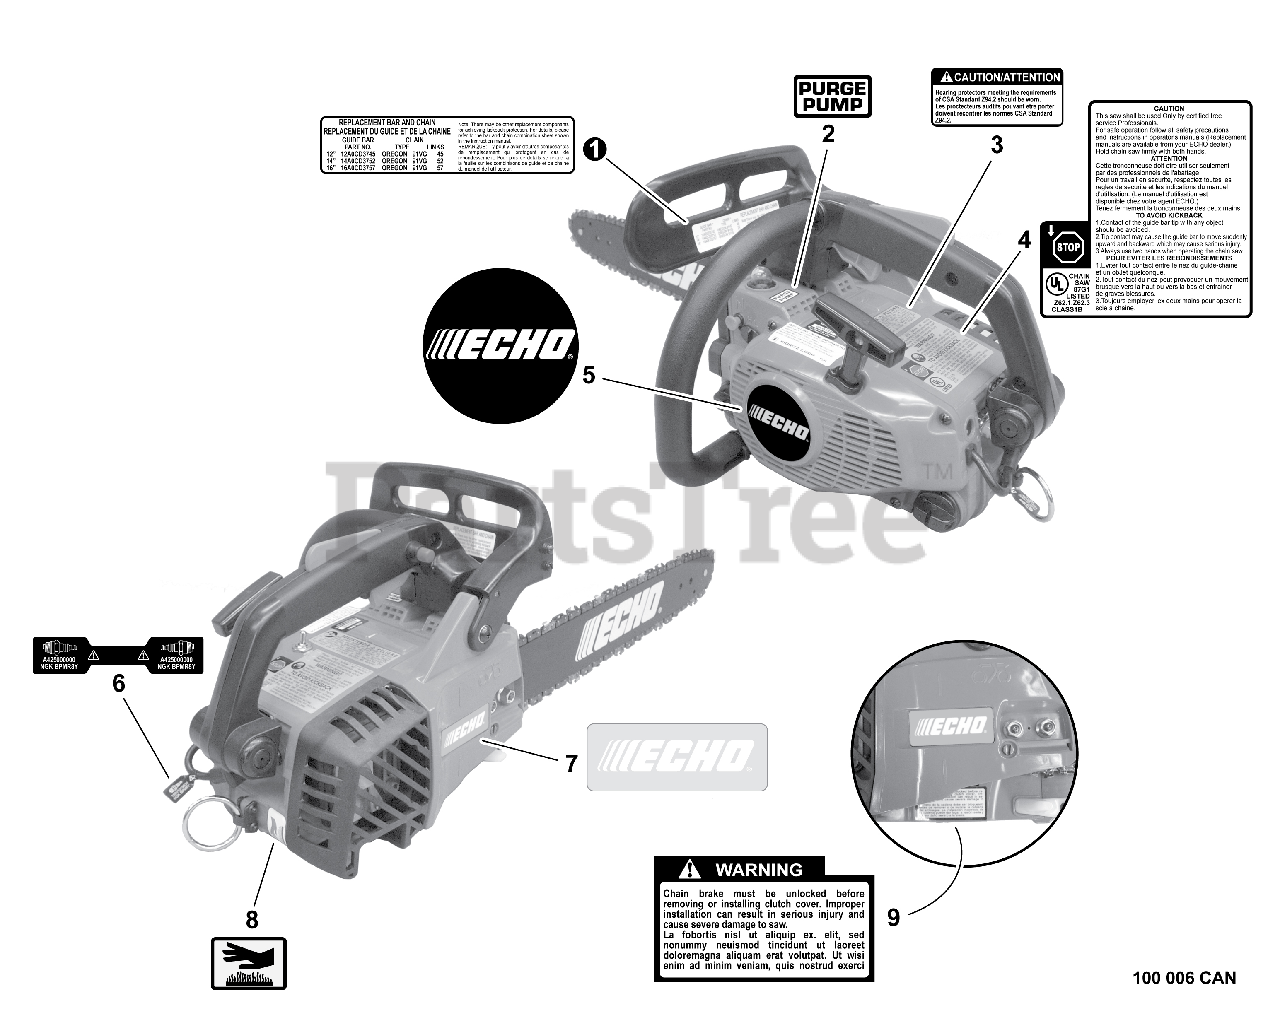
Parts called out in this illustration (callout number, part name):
1	LABEL - BAR & CHAIN
2	LABEL - PURGE PUMP
3	LABEL - NOISE
4	LABEL - KICK BACK
5	LABEL - ECHO
6	LABEL - SPARK PLUG -- BPMR-8Y
7	LABEL - ECHO
8	LABEL - HOT SURFACE
9	LABEL - WARNING
